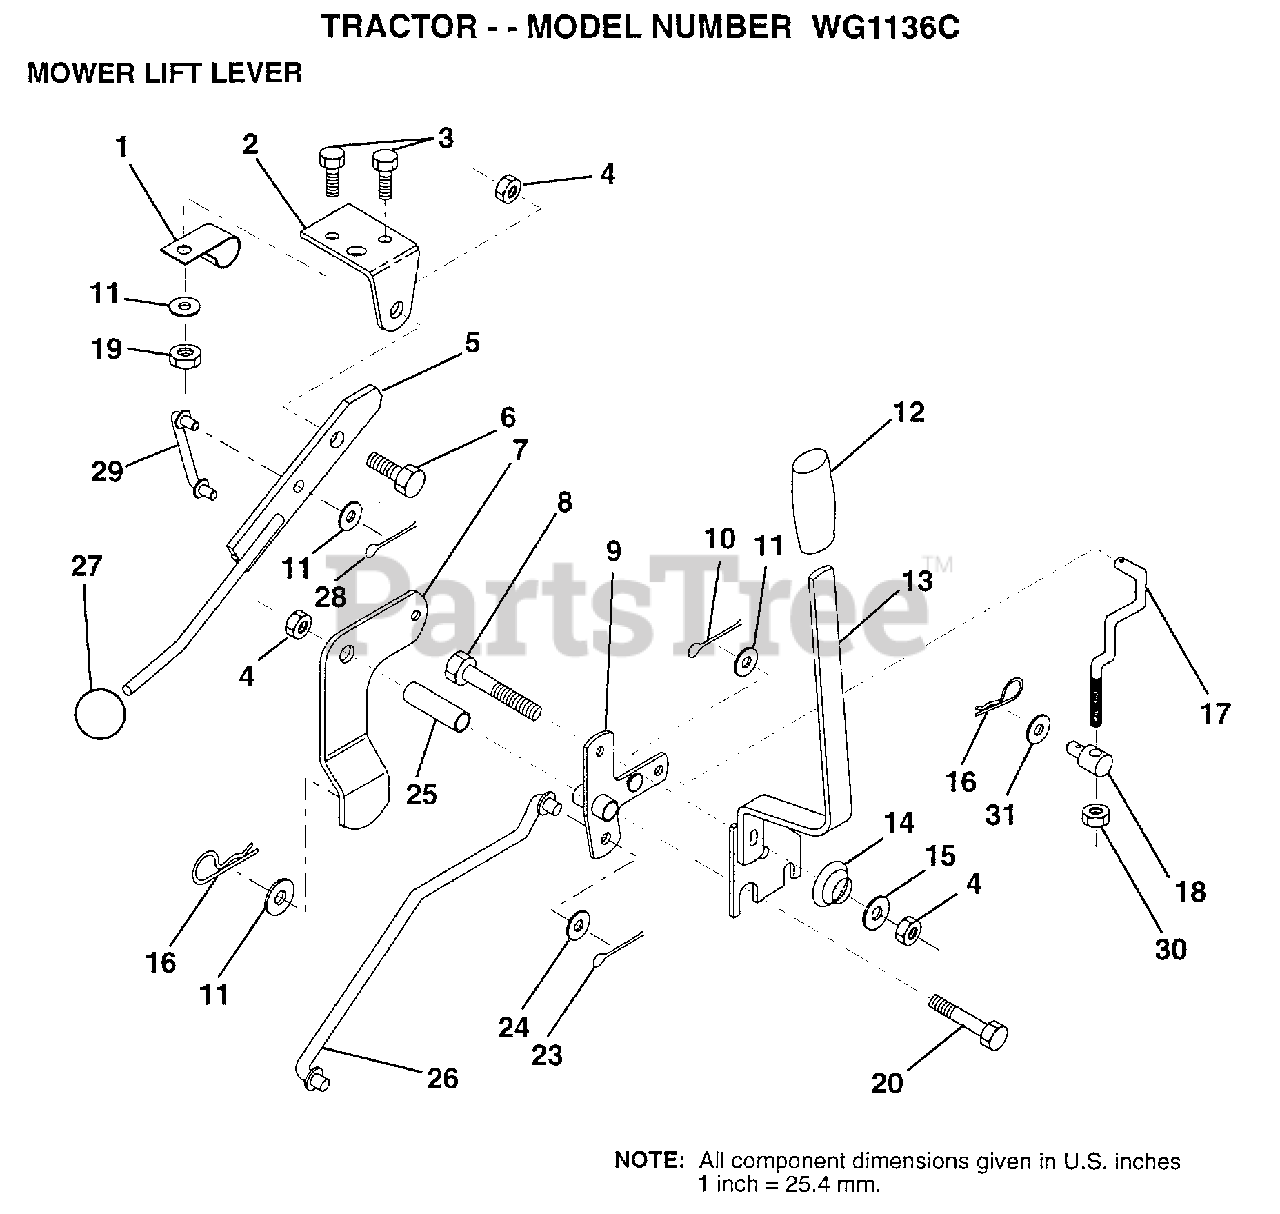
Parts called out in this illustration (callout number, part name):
1	"CLIP,INSULATOR"
2	BRKT CLUTCH
3	BOLT HXHD FIN
5	LEVER.ASM.CLUTCH
6	"BOLT, SHOULDER LT"
7	MWR CLUTCH ARM AS
8	BOLT
9	"BELLCRANK,LIFT"
10	COTTER PIN
11	WASHER
13	HANDLE.ASM.LIFT
14	SPRING COMPRESSIO
15	WASHER T
16	SPRING.RETAINER
17	"LINK,LIFT FRT"
18	TRUNION ADJ
20	BOLT
23	PIN COTTER 1/8
25	TUBE SPACER
26	ROD LIFT MOWER
27	KNOB T(3/8 HOLE)
29	CLUTCH LINK
30	NUT
31	WASHER
